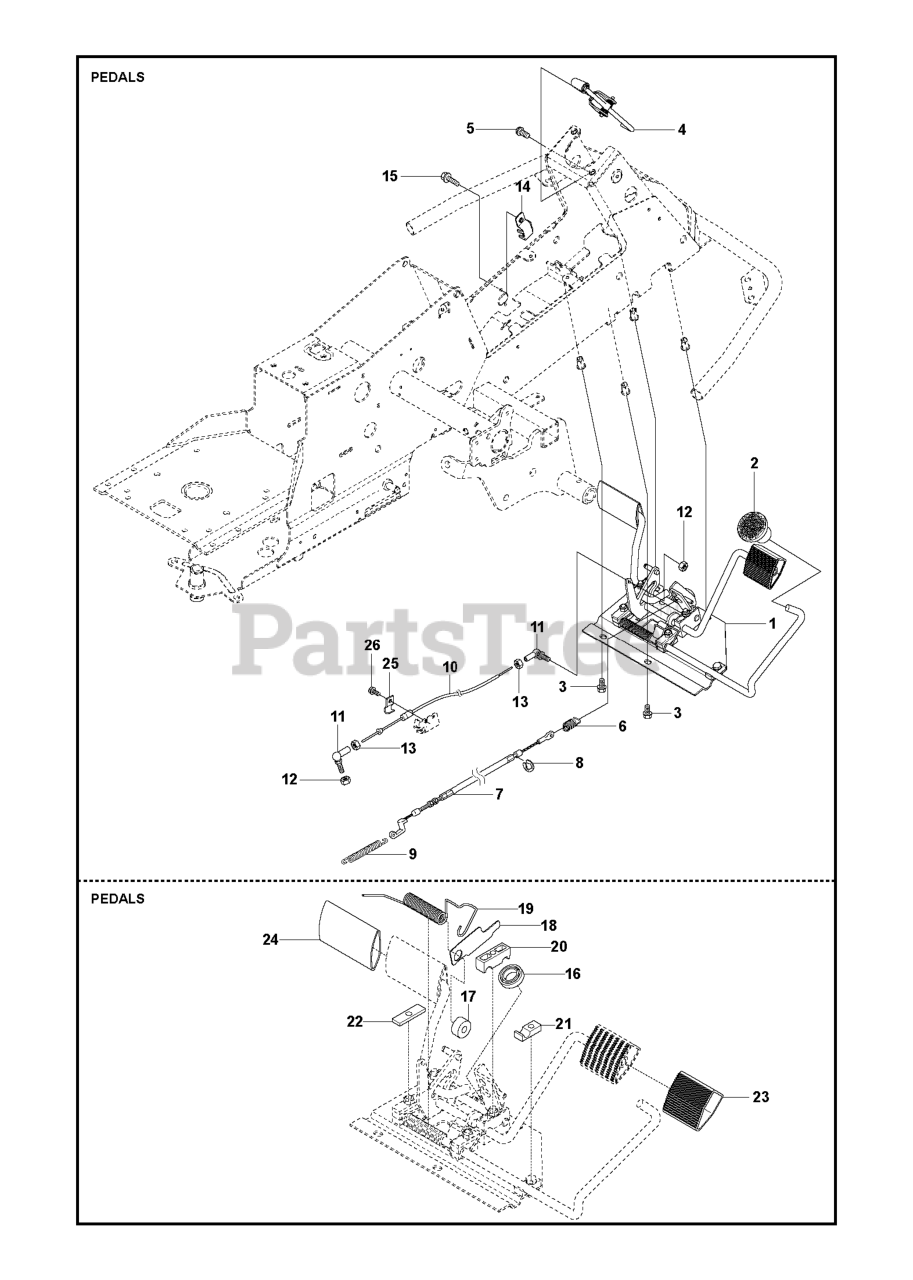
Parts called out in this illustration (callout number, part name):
2	KNOB, THREADED
4	BRAKE LEVER ASSY
7	BRAKE WIRE
10	CONTROL CABLE
11	CONNECTOR, BALL JOINT
12	LOCKNUT M6
15	SCREW EHHFM
16	BALL BEARING 6002-2RS1
17	ROLLER
18	PLATE
19	SPRING
20	PEDAL SHAFT CLAMP
21	SUPPORT
22	PLATE
23	PEDAL RUBBER
24	PEDAL RUBBER L = 102MM
